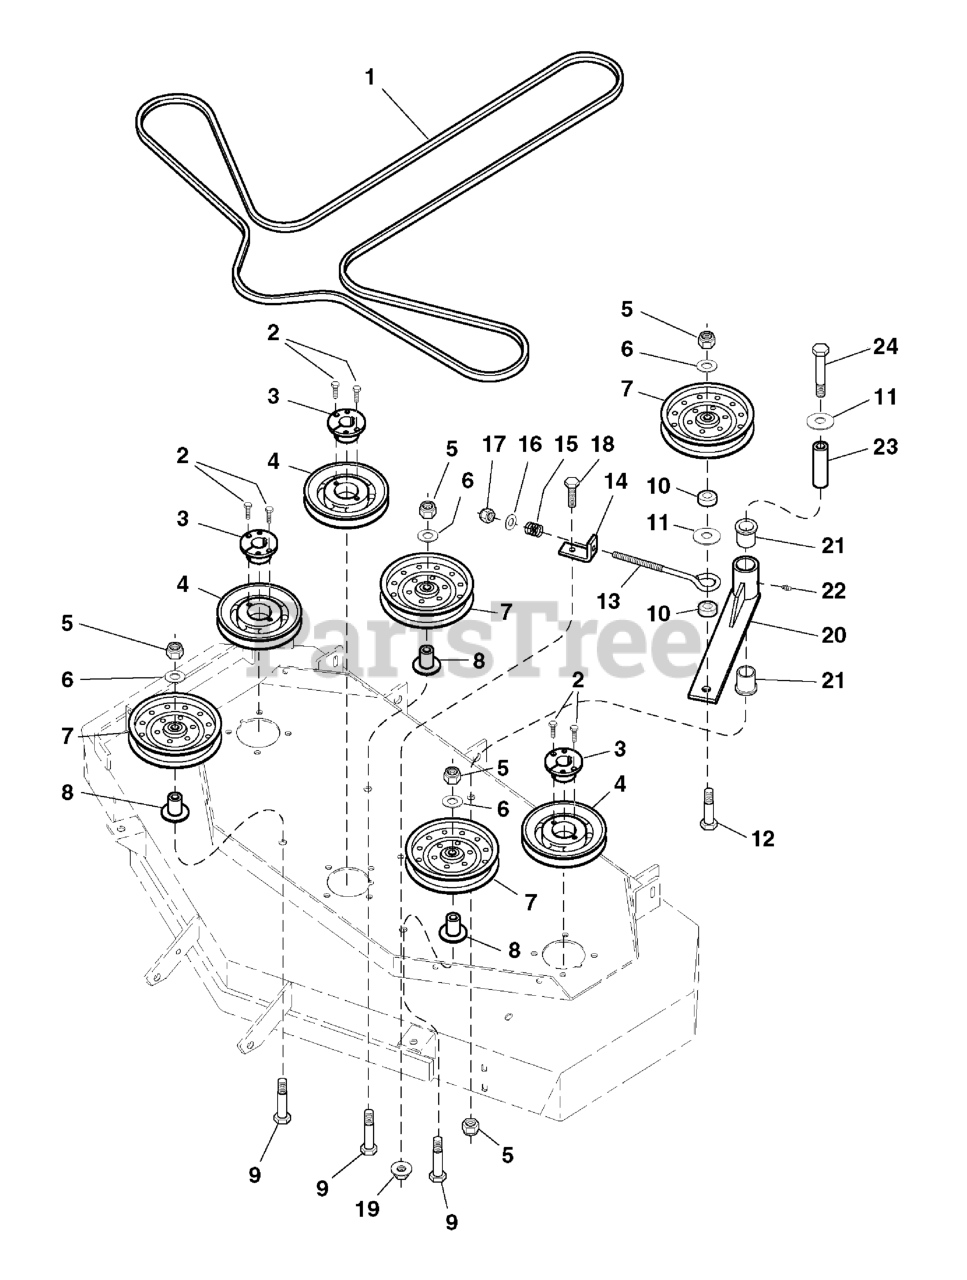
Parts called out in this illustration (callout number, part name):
1	BELT, 5V, 150.90"EL, ARAMID, WRPD, RC
2	BOLT, 1/4-20 X 1" GD5 CZ
3	BUSHING, Tapered Hub
4	PULLEY, Spindle
5	NUT, 1/2-13 HEX NYLON LOCK
6	WASHER, 1/2 SAE
8	IDLER PULLEY MOUNT
9	BOLT, 1/2-13 X 3-1/2, HEX HD, GD5, CZ (SV)
10	SPACER, .52 x 1.00 x .44
11	WASHER, 1/2" USS
12	BOLT, 1/2-13 X 3" GD5 CZ
13	EYEBOLT, 3/8" x 8"
14	SPRING ANCHOR
15	SPRING, Compression
16	WASHER, 3/8 SAE
17	NUT, 3/8-16 HEX NYLON LOCK
18	BOLT, 3/8-16 X 1" GD5 CZ
19	NUT, 3/8-16 Hex Serrated Flange
20	ASSM, IDLER ARM
21	BUSHING, FLANGE
22	GREASE FITTING
23	SPACER, .52 x 1.00 x 3.50
24	BOLT, 1/2-13 x 4-1/2
